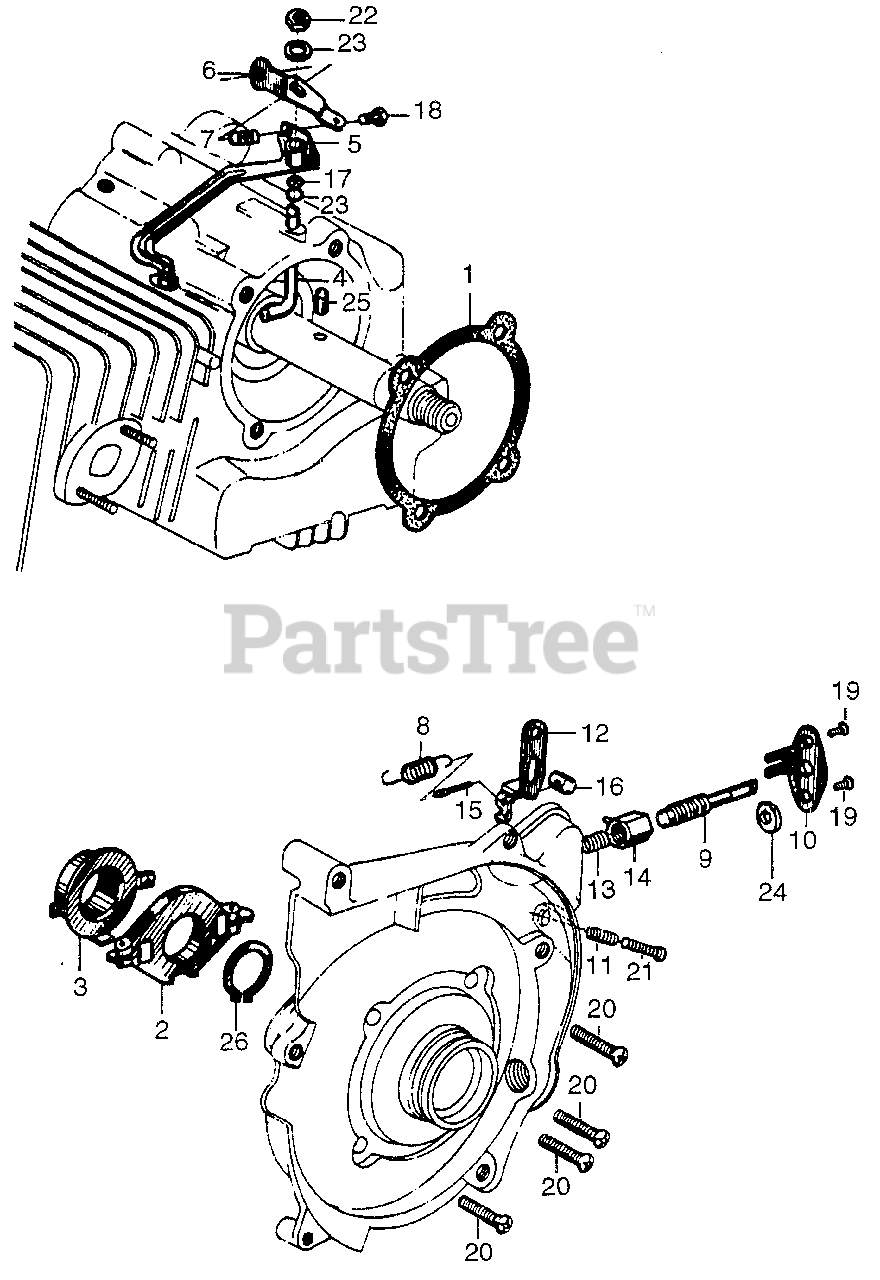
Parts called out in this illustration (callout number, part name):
1	GASKET, STARTER CASE
2	HOLDER, GOVERNOR WEIGHT
3	SLIDER, GOVERNOR
4	SHAFT, GOVERNOR ARM
5	ARM, GOVERNOR (NOT AVAILABLE)
6	PLATE, GOVERNOR ADJUST
7	SPRING, GOVERNOR ARM ADJUST
8	SPRING, GOVERNOR
9	SHAFT, CONTROL ADJUST
10	RETAINER, ADJUST SHAFT
11	SPRING, CONTROL ADJUSTING
12	ARM, CONTROL
13	SPRING, ADJUST SHAFT
14	NUT, CONTROL ADJUST
15	BOLT, SPRING ADJUST
16	NUT, SPRING ADJUST
17	E-RING (4MM)
18	BOLT, SLOT (4X18)
19	SCREW, PAN (4X6)
20	SCREW, PAN (5X22)
21	SCREW, PAN (4X20)
22	NUT, HEX. (4MM)
23	WASHER, FLAT (4MM)
24	WASHER, PLAIN (6MM)
25	PIN, DOWEL (4X65) (NOT AVAILABLE)
26	CIRCLIP (OUTER) (15MM)
